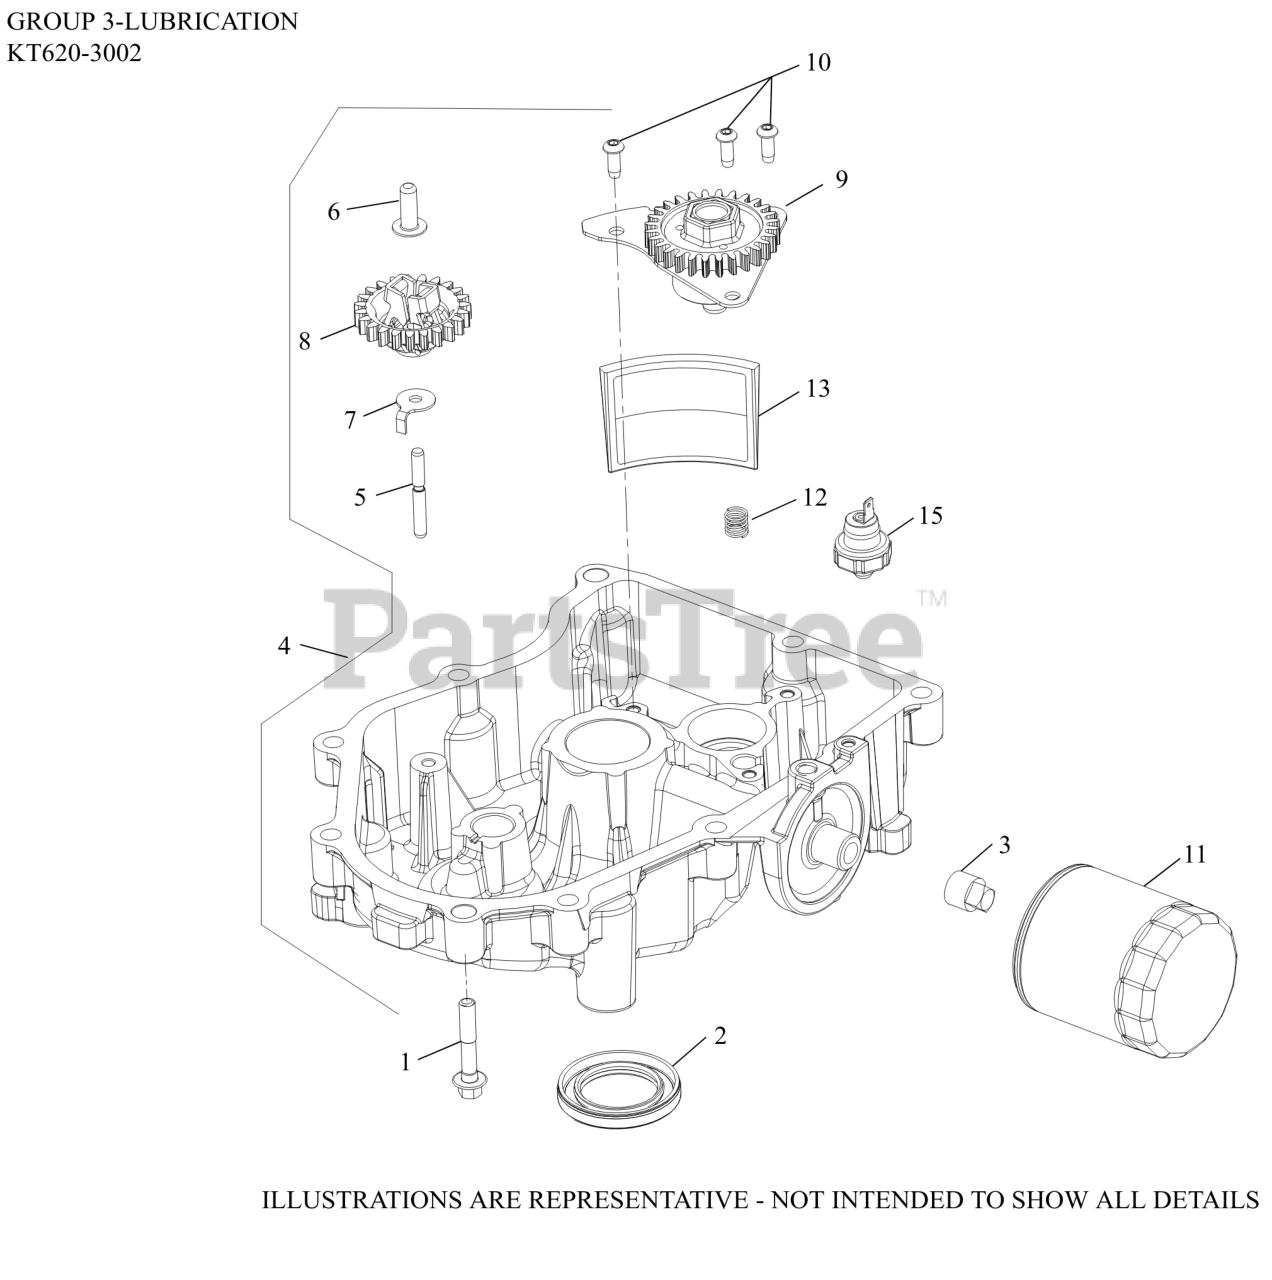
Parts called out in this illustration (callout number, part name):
1	SCREW, FLG M8X1.25X45
3	PLUG, SQ HD PIPE 3/8"
4	PAN ASSEMBLY, OIL-(#3219924S)
5	SHAFT, GOVERNOR GEAR
6	PIN, GOVERNOR REGULATING
7	TAB, LOCKING
8	KIT, GOVERNOR GEAR
9	PUMP ASSEMBLY, OIL
10	SCREW, BUTTON HEAD
11	OIL FILTER
12	SPRING, COMPRESSION
13	SCREEN, OIL
15	SENSOR, OIL PSI 3 TERMINAL
